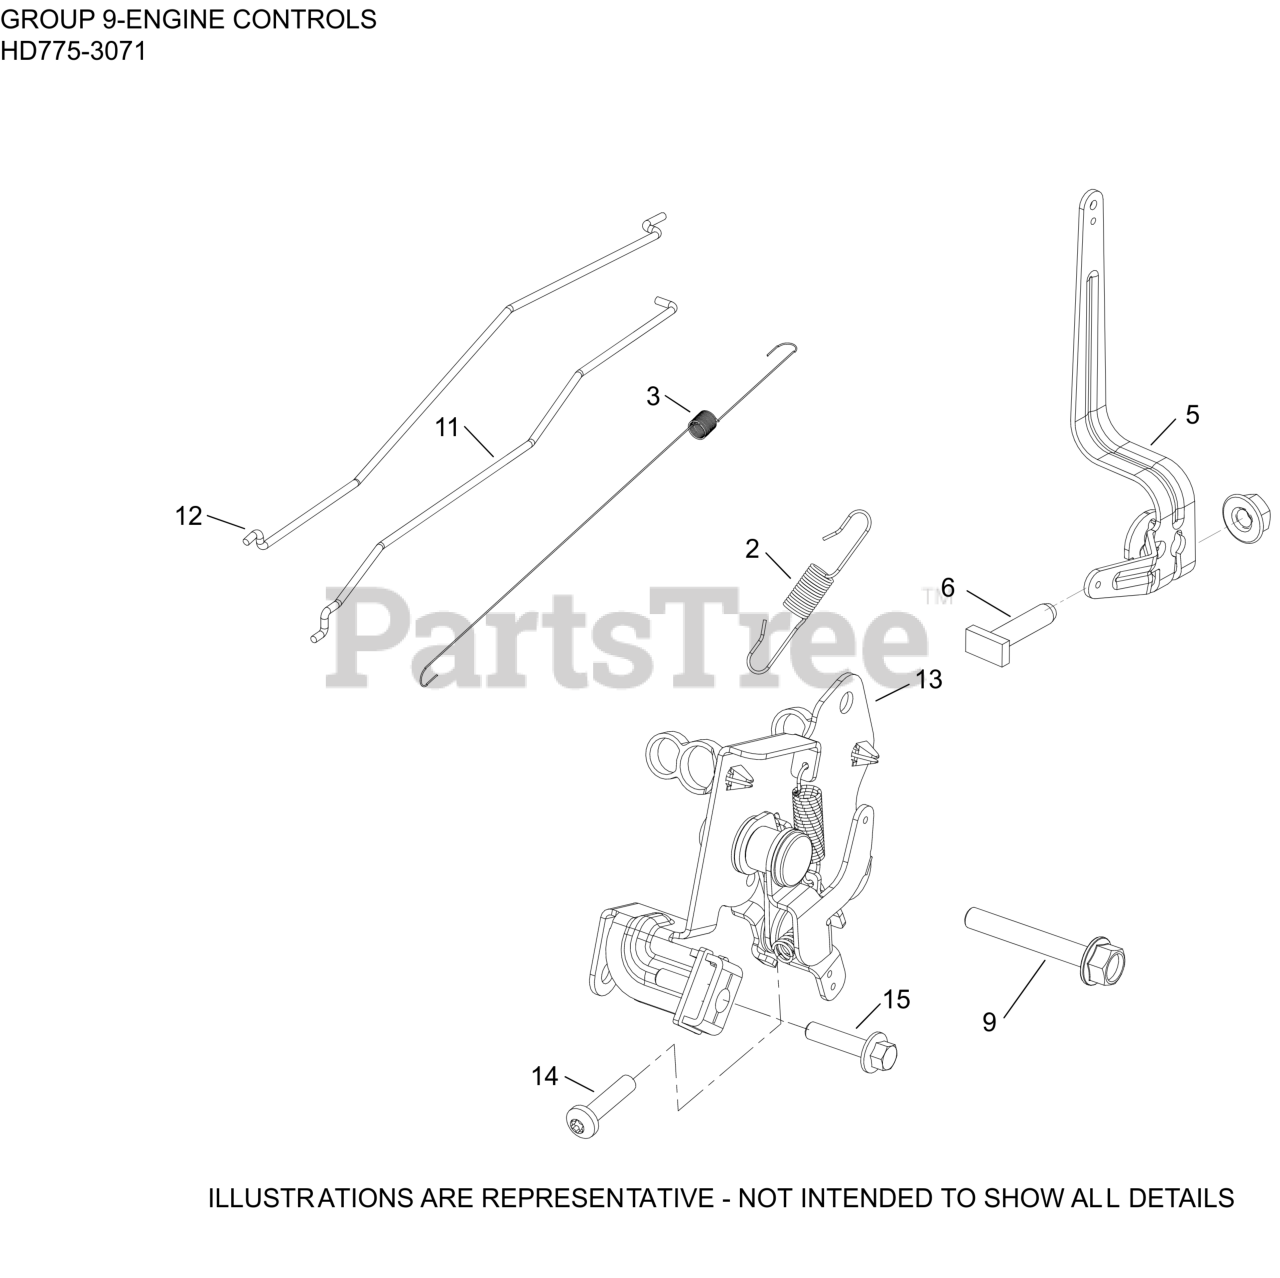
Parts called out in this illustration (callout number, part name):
2	SPRING, GOV (2800-3300 RPM)
3	SPRING, LINKAGE
5	LEVER, GOVERNOR
6	SCREW, RECTANGLE HEAD (M6)
9	SCREW, HEX FLANGE (M6)
11	LINKAGE, GOVERNOR
12	LINKAGE, CHOKE
13	CONTROL ASSEMBLY (VAR. SPEED)
14	SCREW, #25 6-LOBE PAN HD (M5)
15	SCREW, (M5) HEX FLANGE
